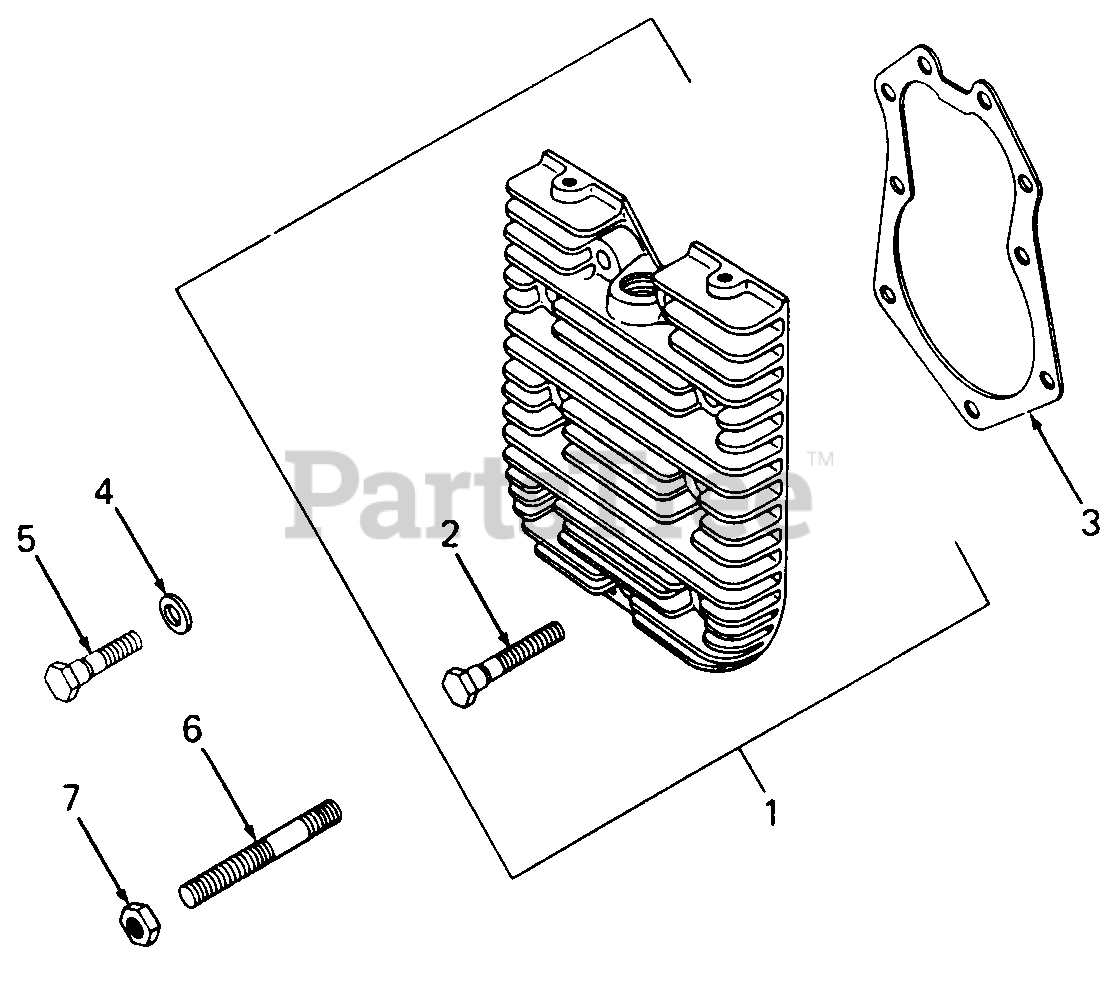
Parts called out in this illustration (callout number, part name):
1	Kit, Cylinder Head
2	Screw, Hex Machine, 5/16-18 X 2.0 Lg
3	Gasket, Head
4	Washer, Plain, 5/16
5	Screw, Hex Hd, 5/16-18 X 1.5 Lg
6	Stud, 5/16-18 X 2.0 Lg
7	Nut, Hex, 5/16-18
